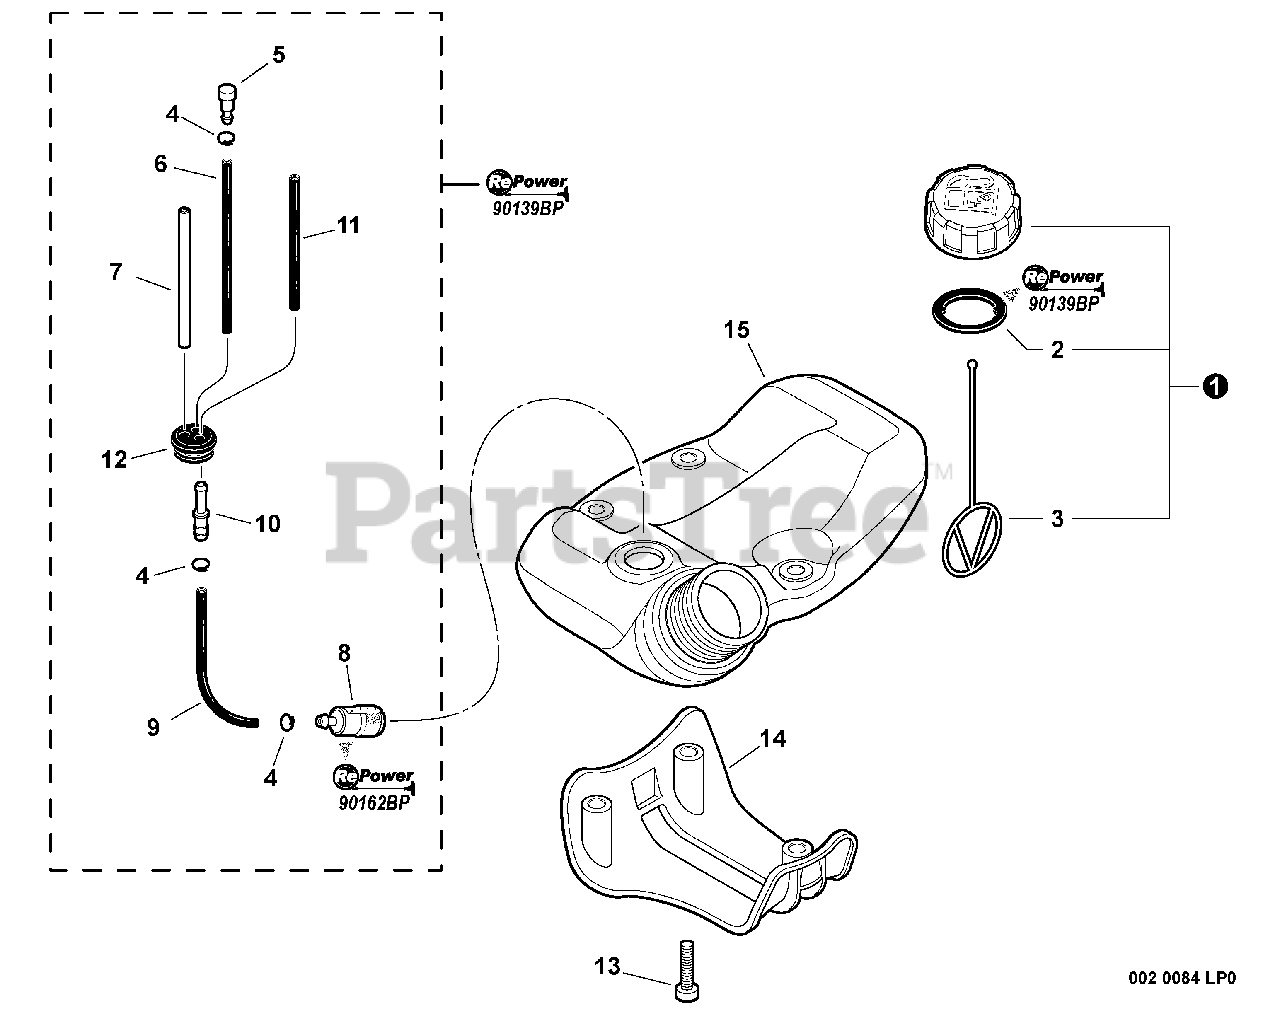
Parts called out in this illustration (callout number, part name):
1	CAP ASSY
2	GASKET, CAP
3	CONNECTOR, CAP
4	CLIP - 6
5	VENT, FUEL TANK
6	PIPE - 3X5X90 -- BLACK
7	PIPE - 3X6X80 -- CLEAR
8	FILTER, FUEL
9	PIPE, FUEL -- BLACK
10	CONNECTOR, PIPE
11	PIPE - 3X5X74 -- BLACK
13	SCREW - 5X25
14	GUARD, FUEL TANK
15	TANK, FUEL
16	RePower TUNE-UP KIT
17	RePower FUEL SYSTEM KIT
